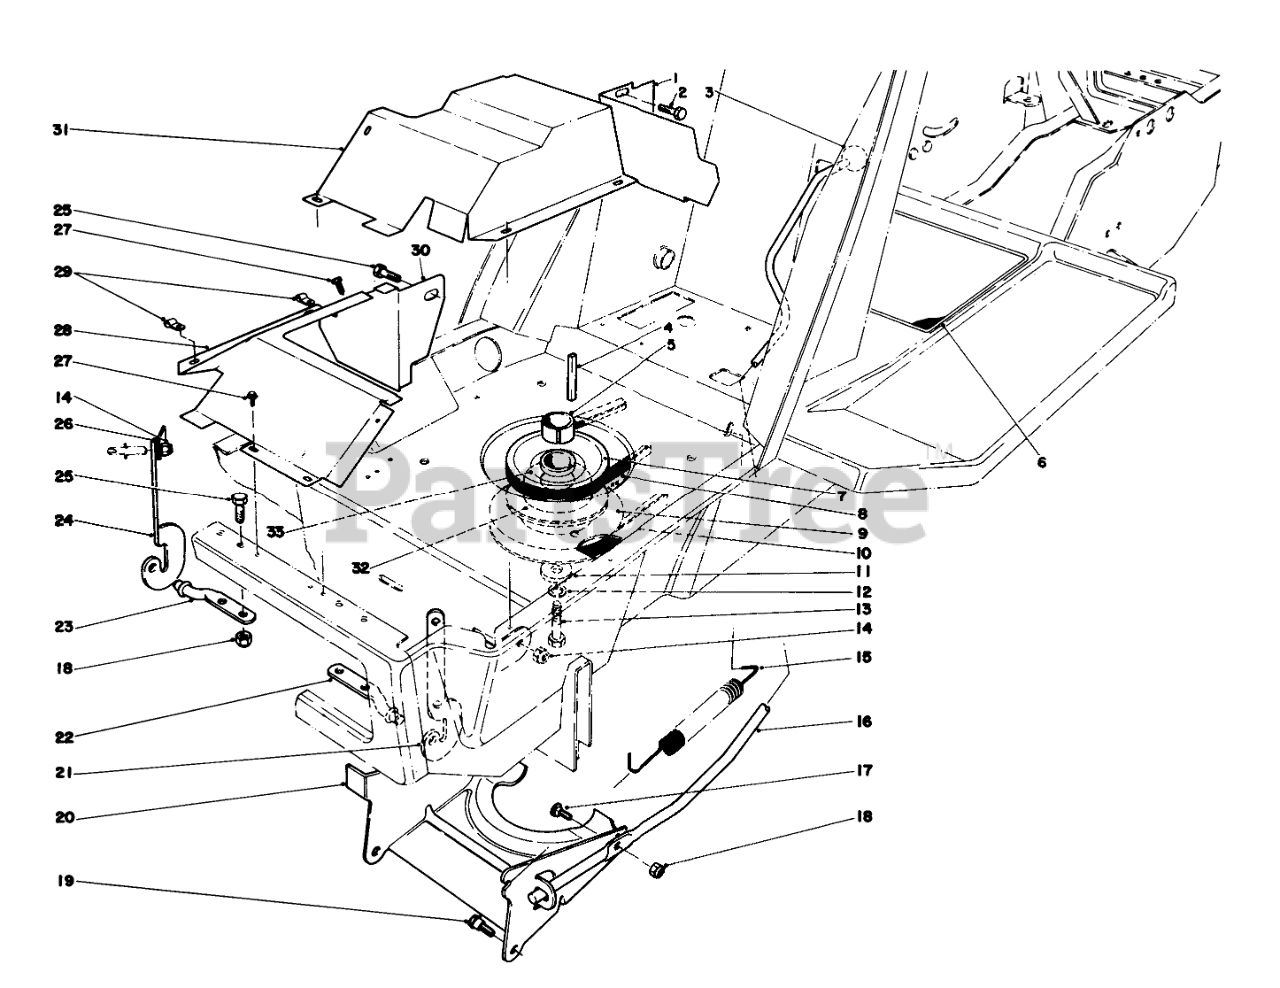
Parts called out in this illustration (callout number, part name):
1	EXH SHIELD SUPT B
2	SCREW-HH
3	Knob
4	KEY-SQUARE
5	PULLEY SPACER
6	OPERATION DECAL
7	Sheave
8	V BELT
9	Clutch & Brake-Deck (Incl. Ref. #32 & 33)
10	V BELT
11	WASHER
12	WASHER-LOCK
13	SCREW-HH
15	TRACTION SPRING
16	Engagement Lever
17	Bolt
18	NUT-LOCK, CONE
19	Shoulder Screw
20	CLUTCH ACTUATOR R
21	L.H. HINGE BRACKET
22	LH HOOD HINGE PIN
23	RH HOOD HINGE PIN
24	RH HINGE BRKT
25	SCREW-HH
26	SCREEN SUPT BRKT
27	SCREW-HWHTF
28	Heat Shield
29	CABLE CLAMP
30	Support Heat Shield
31	HEAT SHIELD WA B
32	CLUTCH PLATTER
33	SPRING WASHER
